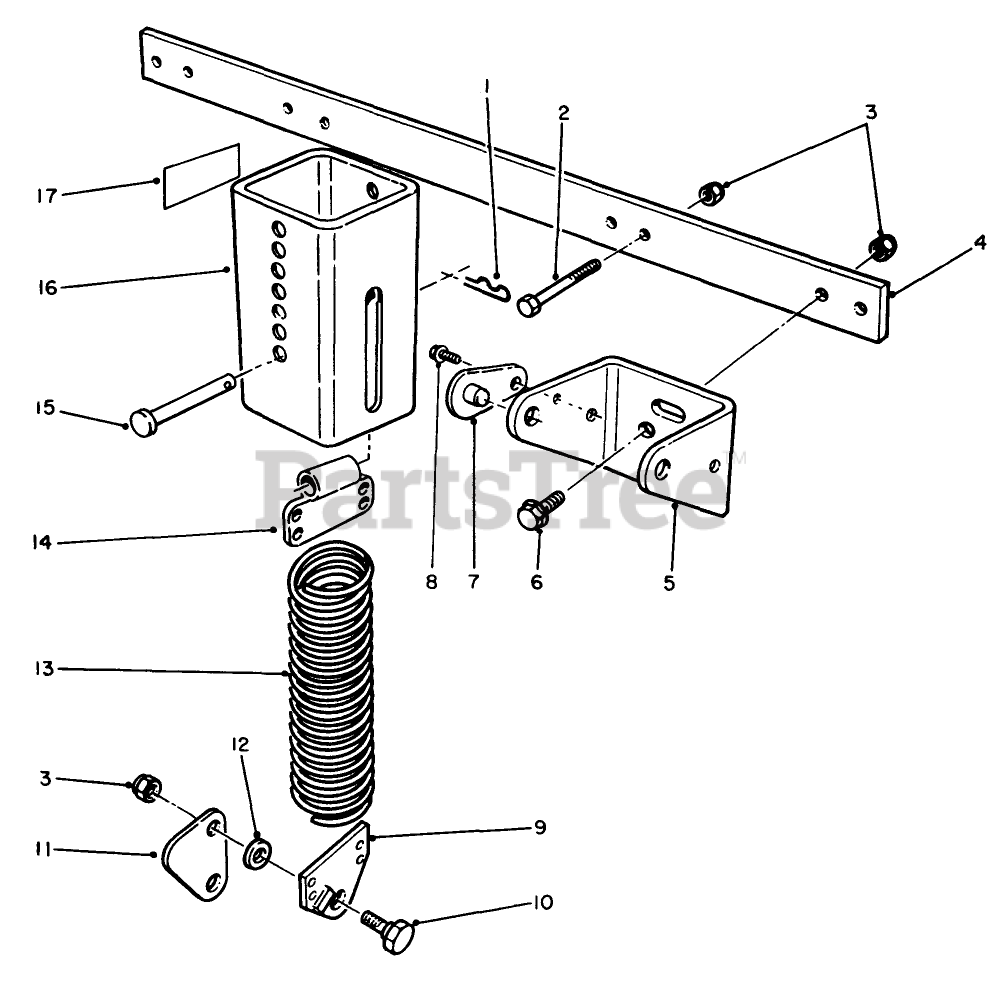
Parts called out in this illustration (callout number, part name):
1	PIN-HAIR
2	SCREW-HH
3	NUT-LOCK, NI
4	Adapter
5	Bracket-Support
6	SCREW-HHF
7	PIN-LOCK
8	SCREW
9	End Spring
10	BOLT-SHOULDER
11	Link
12	WASHER-FLAT
13	Spring-Extension
14	End Spring
15	PIN-CLEVIS
16	Asm-Spring Cover
17	DECAL-WARNING
